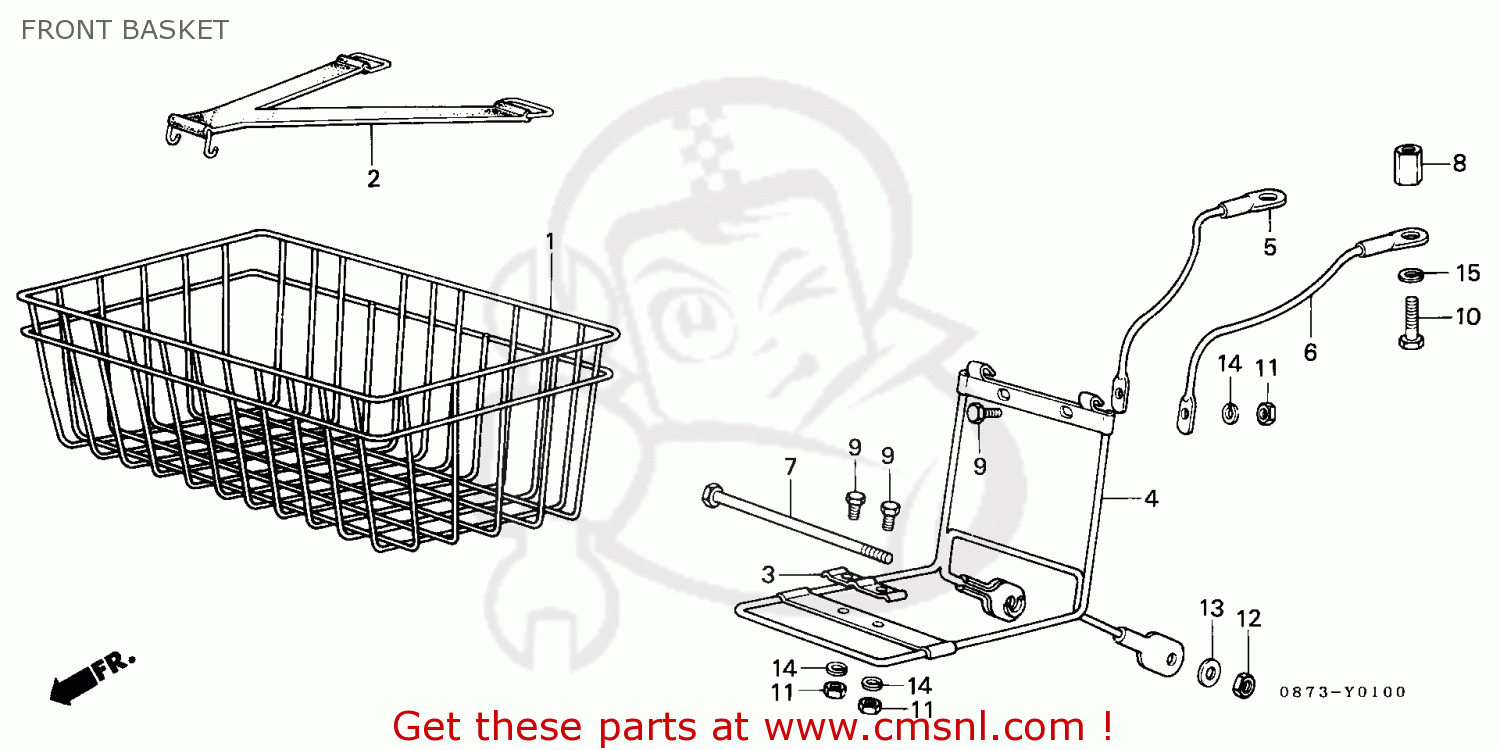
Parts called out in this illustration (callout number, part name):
1	BASKET,FRONT
2	RUBBER BAND
3	FIXING PLATE
4	CARRIER,FRONT
5	STAY,R FR.CARRIER
6	STAY,L.FR.CARRIER
7	BOLT, FR.CARRIER SETTING
8	NUT,STAY,MUFFLER
9	BOLT,HEX 6X12
10	BOLT,HEX.,8X20
11	NUT,HEX 6MM
13	WASHER,PLAIN,8MM
14	WASHER,SPRING,6MM
15	SPG-WASHER 8MM
